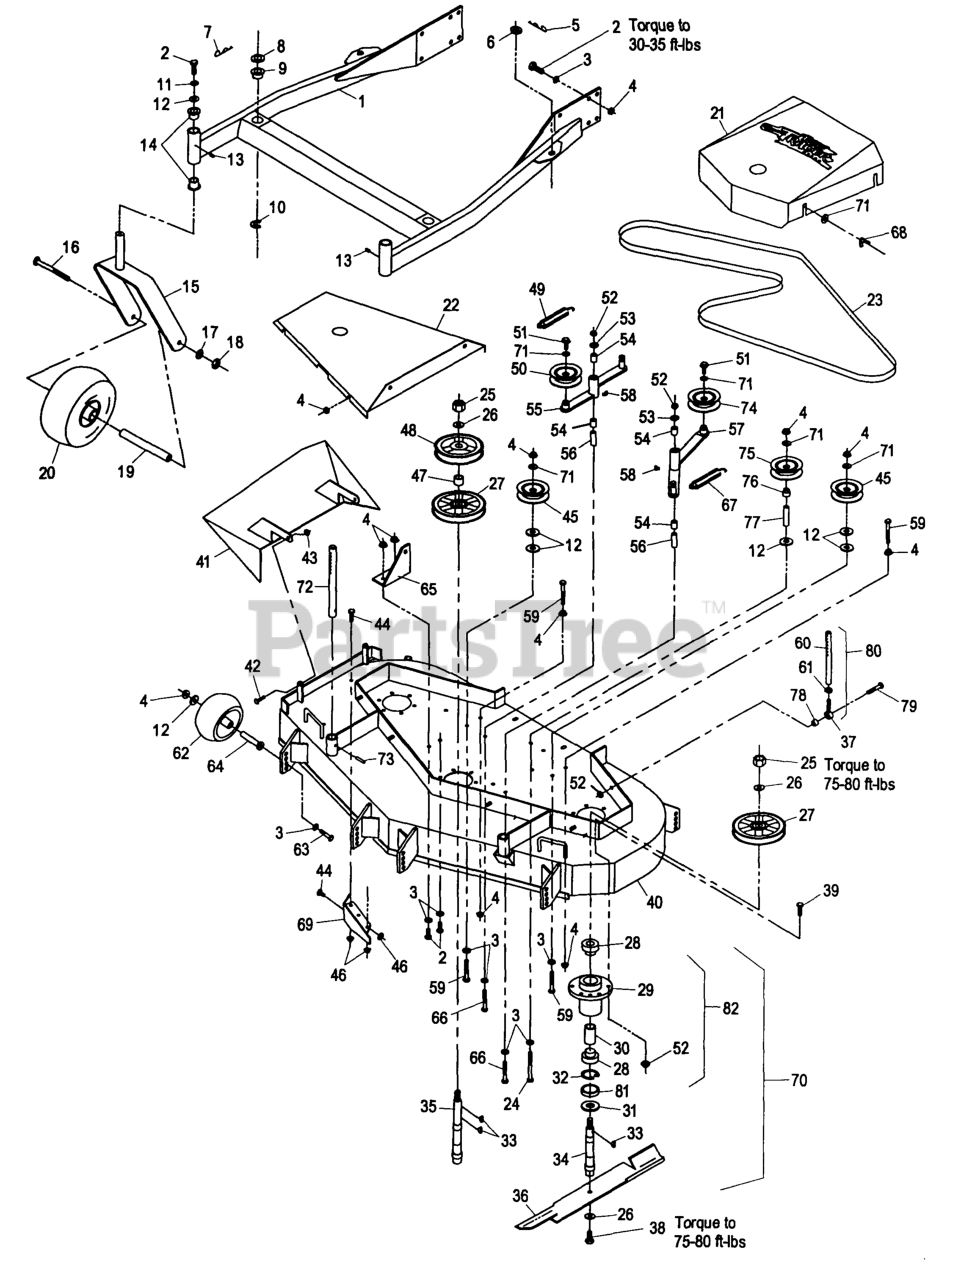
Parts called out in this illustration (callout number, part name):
5	PIN,HAIR COTTER
8	SPACER-DECK SUPPORT
9	BUSHING-DECK
12	WASHER
14	BEARING-FLANGED
23	BELT,BLADE DRIVE
26	WASHER-SPRING
27	SHEAVE,BLADE DRIVE
28	BEARING
30	SPACER-BEARING
31	GUARD-BEARING, BOTTOM
34	SHAFT,SPINDLE SHORT
35	SHAFT,SPINDLE LONG
41	WLD,CHUTE DISCHARGE
45	IDLER,PULLEY
47	SPACER-TUBE
48	SHEAVE,MOWER DRIVE
49	SPRING-EXTENSION
50	IDLER,PULLEY
54	SLEEVE-BEARING
55	ASM,IDLER ARM
56	BUSHING-PIVOT, IDLER
57	ASM,IDLER ARM
60	LINK, DECK SUPPORT
61	BALLJOINT
62	ROLLER-SCALP, ANTI
64	BUSHING-ROLLER
65	BRACKET,SPRING ANCHOR
66	SCREW-HH
67	SPRING-EXTENSION
68	NUT-WING
69	WLD,BAFFLE DISCHARGE
70	CUTTER HOUSING ASSY,CEN
72	ROD,DECK SUPPORT
74	PULLEY-IDLER
75	PULLEY-IDLER
76	BUSHING,IDLER
77	SPACER-FENDER
81	SPACER-PULLEY/BEARING
